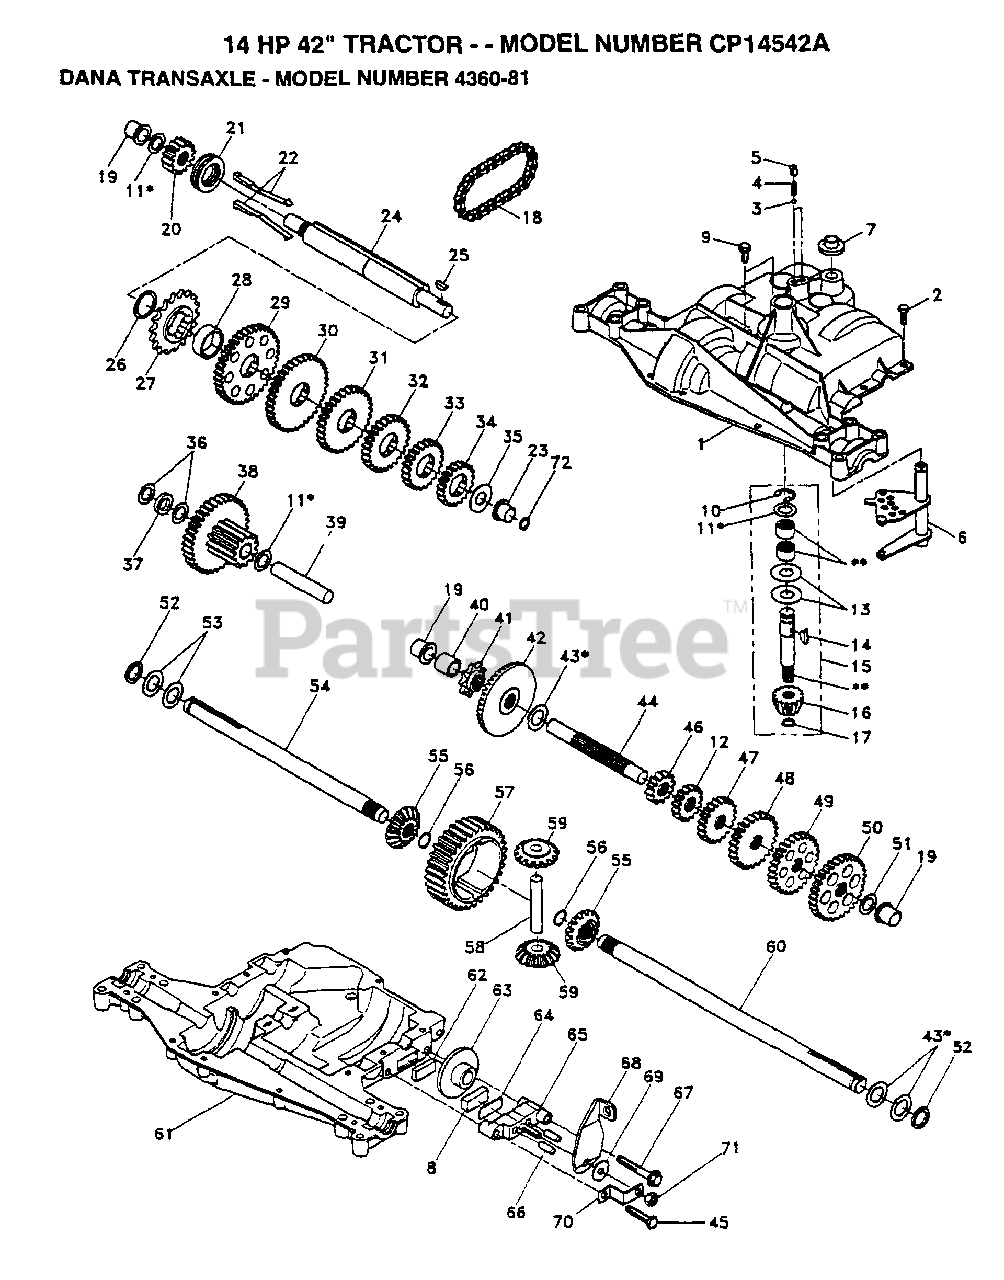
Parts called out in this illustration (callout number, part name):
1	HOUSING UPPER TRN
4	"SPRING, DETENT LT"
5	"SCREW, SET LT"
6	SHIFTER.ASM.KIT.
7	SHIFTER BOOT
8	PUCK T
9	SCREW TAP W/SEAL
11	ASM KIT SHIM 4689
12	GEAR SPUR 15 TTH
13	WASHER T
14	KEY WOODRUFF-DANA
17	"RING,RETAINING LT"
18	"CHAIN,24 PTCH LT"
19	BEARING.FLNG.5510
20	GEAR SPUR 14 TTH
21	COLLAR CLUTCH
22	KIT.ASM.CLUTCH KY
24	SHAFT INTERM DANA
25	WOODRUFF KEY
26	"RING,RETAINING LT"
27	SPROCKET 18T T
28	SPACER YT
29	GEAR SPUR 37 TTH
30	GEAR SPUR 35 TTH
32	GEAR 25T LT
33	GEAR SPUR 22 TT
34	SPUR GEAR 19T
35	"WASHER, PLAIN LT"
36	WASHER 025
37	SPACER
38	ASSM GEAR COMB
39	SHAFT IDLER
40	SPACER T
41	SPROCKET 9T LT
43	ASM KIT SHIM
44	SHAFT T
45	"SCREW, TAPPING LT"
46	GEAR SPUR 12 TTH
48	"GEAR, SPUR 25T LT"
49	GEAR 28T T
50	"GEAR, SPUR 31T LT"
51	WASHER 060
52	NEOPRENE WASHER
53	WASHER 031
55	GEAR LT
56	"RING,RETAINING LT"
58	SHAFT T
59	"GEAR,MITER 15T YT"
61	HOUSING LOWER TNS
62	PUCK T
63	BRAKE DISC. T
64	SPACER LT
66	PIN T
69	WASHER LT
71	NUT.LOCK.5/16-24
72	SEAL OIL DANA5416
